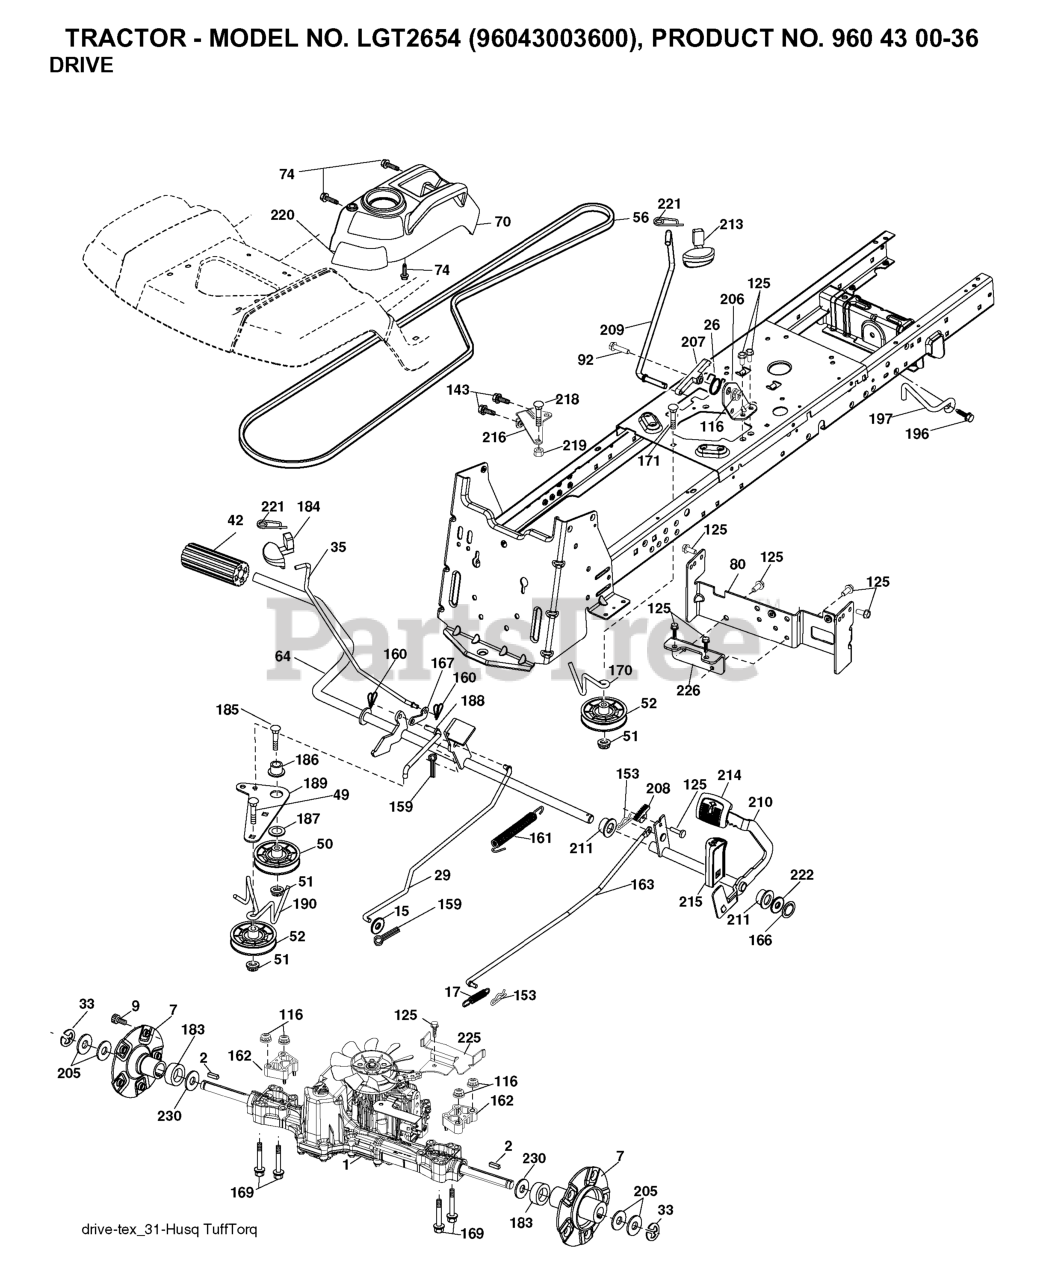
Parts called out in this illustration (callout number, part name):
1	TRANSAXLE.K46BN.PEDAL CONTROL
2	KEY.SQUARE.187X2.500
7	HUB.ASM.WHEEL.REAR.22"
15	WASHER
17	SPRING.BRAKE.K46
26	SPRING.RETURN.CRUISE
29	ROD.BRAKE.K46
35	ROD.BRAKE.PARKING.GT.H
42	PEDAL COVER T
50	IDLER.FLAT.910.OFFSET
51	NUT LOCK FLG 3/8-16 UNC
52	IDLER.V-GROOVE.910.OFFSET
56	V-BELT.MOWER.92.40.42/K46
64	SHAFT.ASM.PEDAL.BRK.CNTR
70	RP CONSOLE.ASM.PCH.W/TB
74	SCREW.HI-LO.CONSOLE
80	STRAP.TORQUE.HG3000/K46
96	BOLT
116	NUT LOCK HEX FLANGE 5/16-18
125	SCREW
143	Screw 5/16-18 x 1/2 Hex, Self Tapping 5/16-18 x 1/2
153	RETAINER M
159	COTTER PIN
160	RETAINER CLIP
161	SPRING.RETURN.CLUTCH.2006
162	SPACER.TRANSAXLE.18&22
163	ROD.CONTROL.PEDAL.K46
166	NUT.PUSH.625.2006
167	LATCH.BRAKE.SPRING
169	BOLT.HEX.FLNG.5/16-18X3.75
170	KEEPER.V-IDLER.CENTER.
183	SPACER.SPLIT.800X.350
184	HANDLE.PARKG.BRK.HUSQ X667
186	SPACER.RETAINER
187	WASHER 12/32X2X10GA
188	RP.LINK.CLUTCH.GROUND.DRIVE
189	BELLCRANK.GROUND.DRIVE.TEX.
190	KEEPER.BELLCRANK.DRIVE
196	SCREW 3/8-16X1
197	BRKT.ANIT-ROTATION.CLUTCH
206	BRKT.MOUNT.LATCH.CRUIS
207	LATCH.CONTROL.CRUISE
208	GEAR.SECTOR.CONTROL.CR
209	ROD.CONTROL.CRUISE.GT.
210	ROCKER.ASM.PEDAL.CONTR
211	BEARING.NYLON
213	KNOB.CONTROL.CRUSIE.HU
214	PEDAL.FORWARD.TEX.GT.4
215	PEDAL.REVERSE.TEX.GT.4
216	BRACKET.PULLEY.IDLER.W/TEX
218	BOLT.5/16-18X1-1/4 FULL.THREAD
219	NUT.CENTERLOCK.5/16-
220	REFLECTOR.RH.TEX GT
221	RETAINER.SPRING.CLIP.H
222	WASHER
225	KEEPER.BELT.TRANSAXLE.K46
226	BRKT.MOUNT.TORQUE.K46.
230	WASHER.HARDENED
